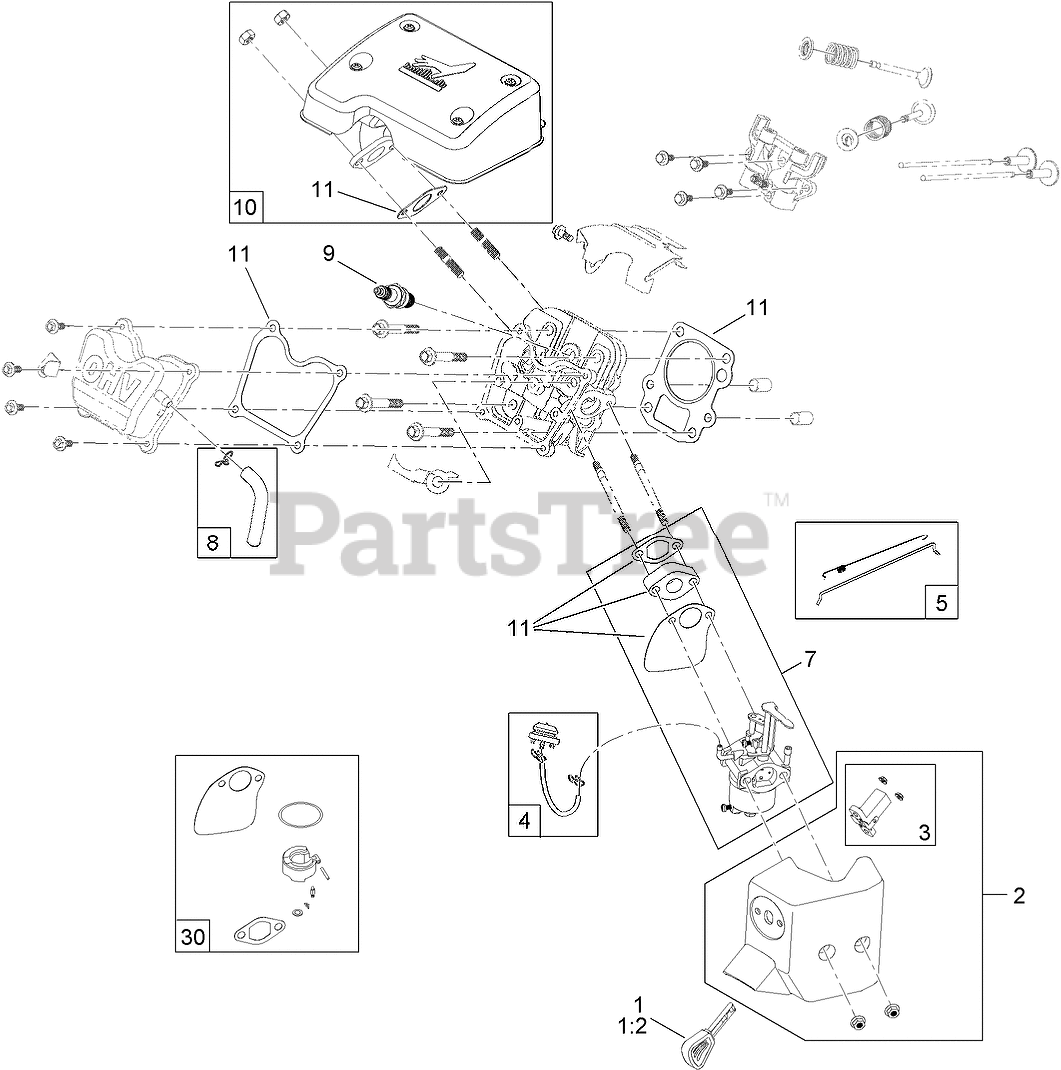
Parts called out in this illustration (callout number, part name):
1	KEY AND LANYARD KIT
2	HEATER BOX KIT
3	SWITCH KIT
4	PRIMER BULB KIT
5	GOVERNOR KIT
7	COMPLETE CARB SERVICE KIT
8	BREATHER TUBE KIT
9	SPARK PLUG
10	MUFFLER KIT
11	GASKET, SEAL AND O-RING KIT
30	CARB FLOAT AND NEEDLE KIT
